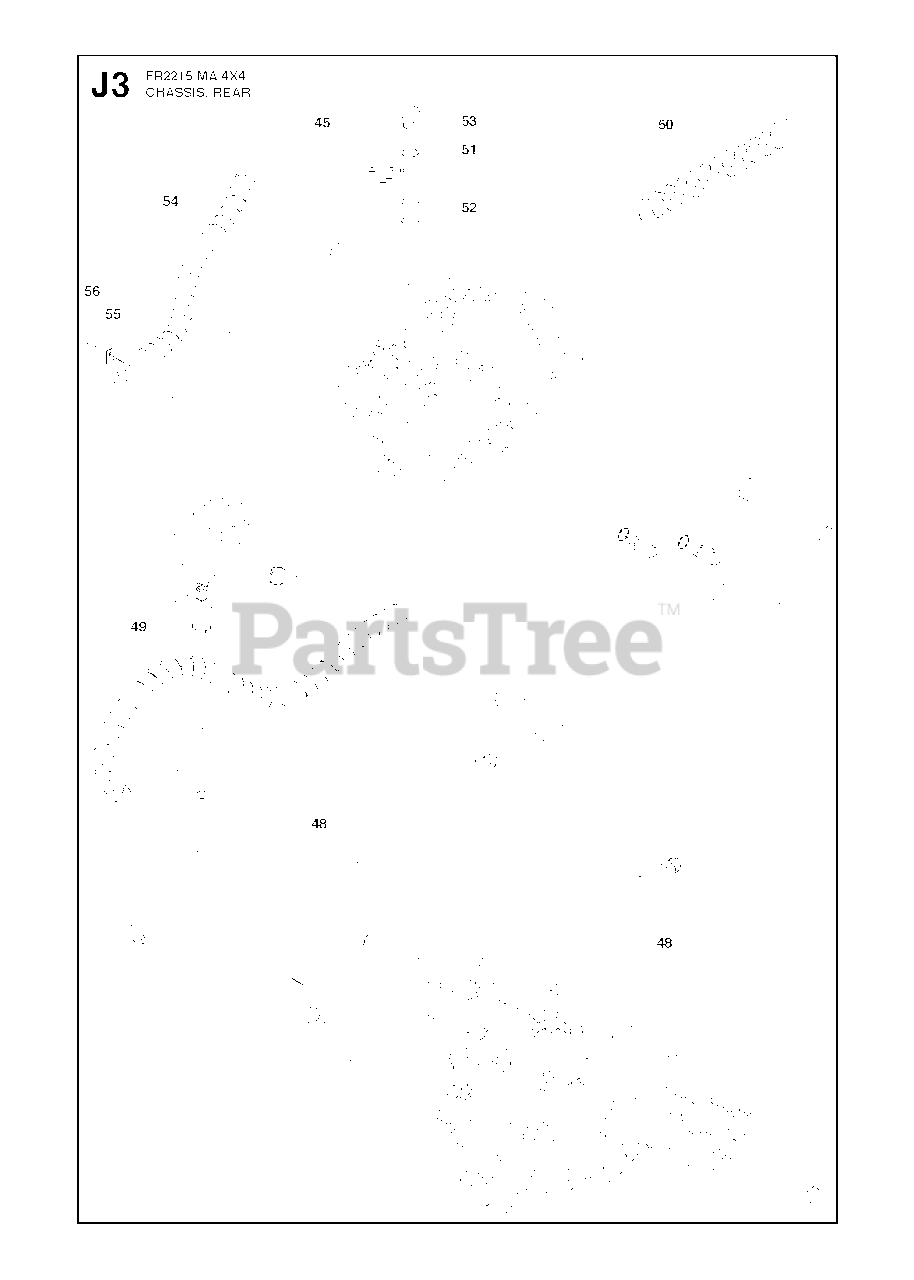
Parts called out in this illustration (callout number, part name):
45	HYDRAULIC HOSE
48	HYDRAULIC HOSE
49	HOSE CLIP
50	PROTECTOR
53	PIPE FITTING
54	HOSE GUARD
55	HOSE CLAMP
